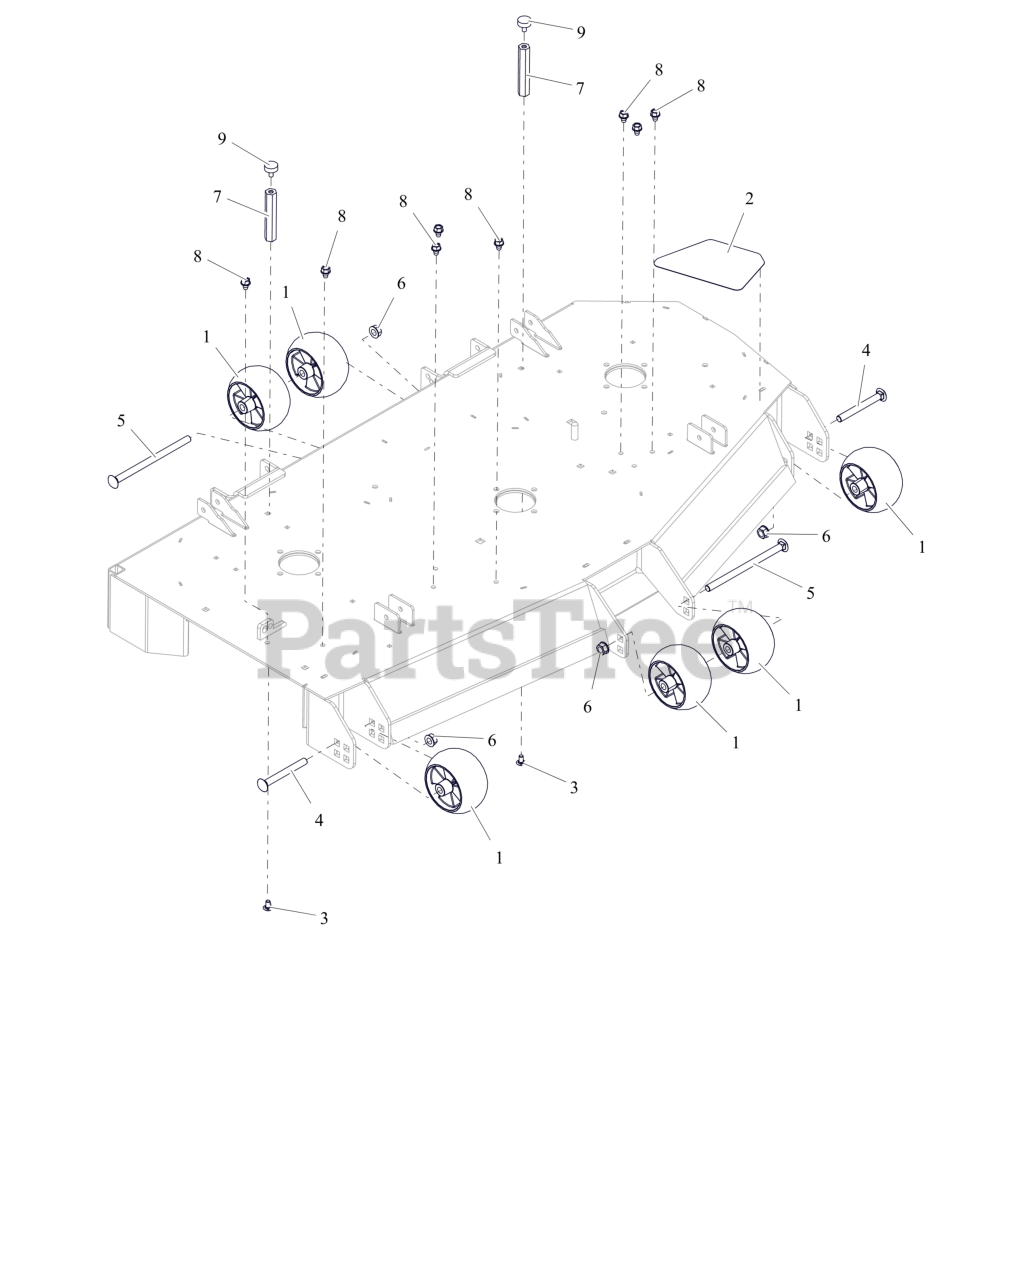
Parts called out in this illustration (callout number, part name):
1	WHEEL, ANTI SCALP - 5X3 CTR W/RIBS
2	GRIP, STEP ANTI SKID
3	BTL,RHSSN .313-18 X 0.625 G5 ZCC
4	BLT,RHNS .50-13X4.50 G5 ZCC NS
5	BLT,RHSN .50-13X8.00 G5 ZCC NS
6	NUT-LK-CTR-FLG .500-13 GG ZCC
7	NUT, COUPLING .312-18 X 4.295
8	SCR,TAP .375-16X.50 HWH TR ZCC
9	BUMPER, RUBBER
